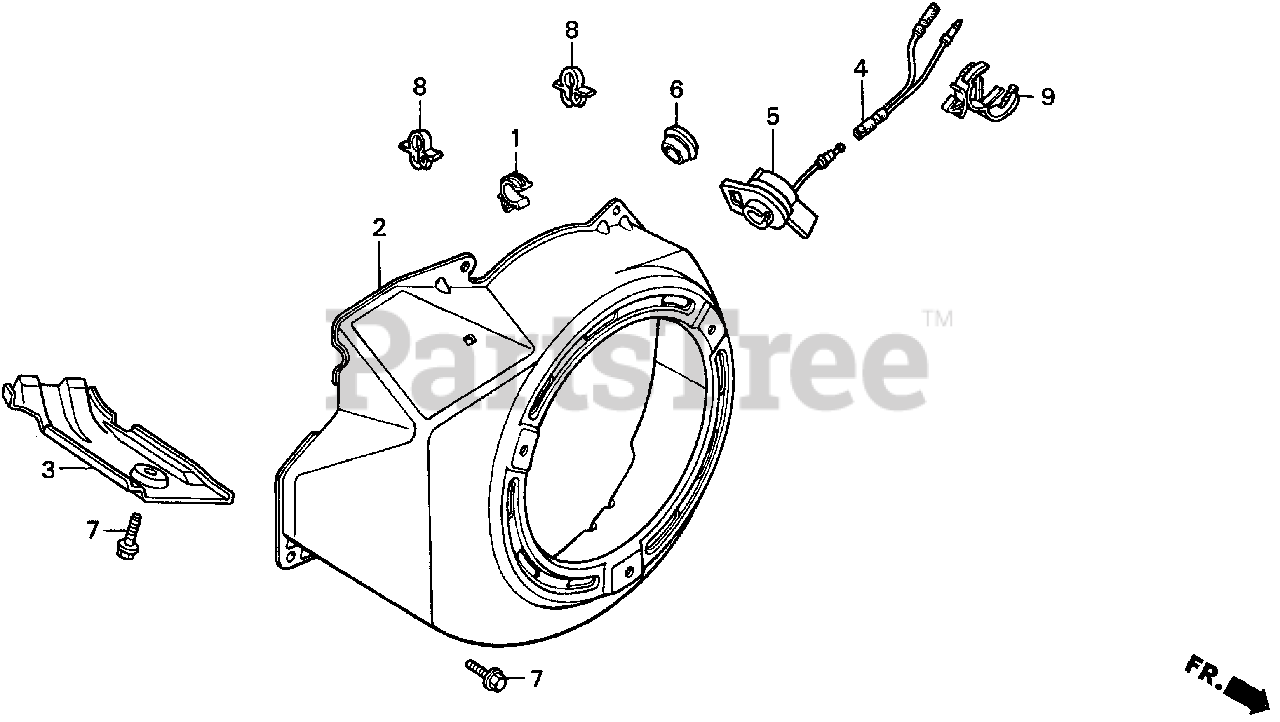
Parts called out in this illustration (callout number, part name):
1	CLIP, TUBE
2	COVER, FAN *NH105* (MAT BLACK)
3	SHROUD
6	GROMMET, DRAIN HOLE
7	BOLT, FLANGE (6X12) (CT200)
9	CLIP, WIRE HARNESS
